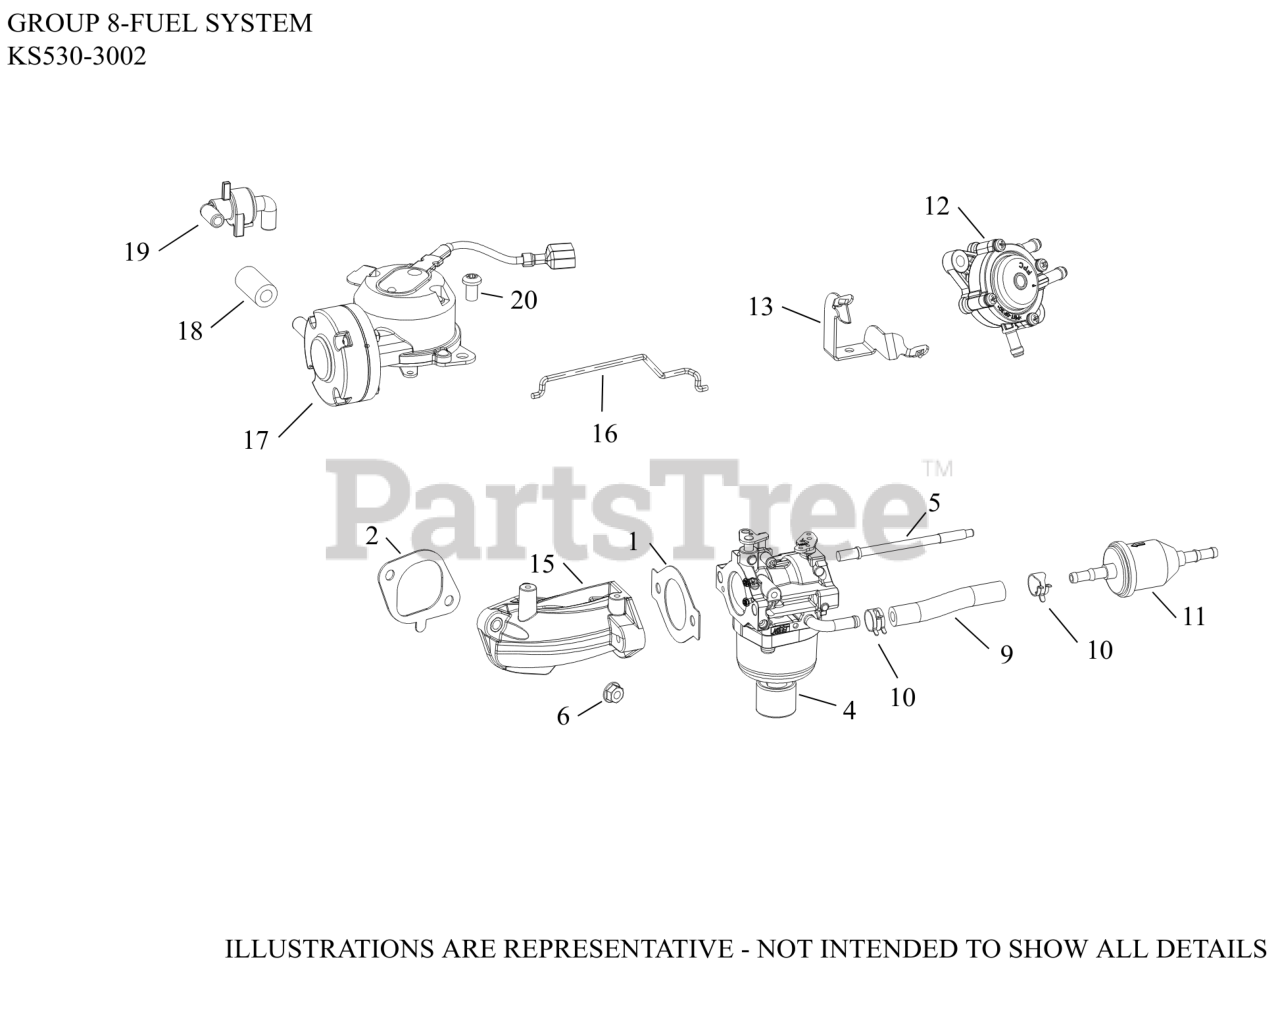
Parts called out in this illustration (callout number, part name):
1	GASKET, CARBURETOR (THROTTLE)
2	GASKET, INTAKE MANIFOLD
4	KIT,CARB(NIKKI)
5	STUD, CARBURETOR
6	NUT, FLG M6X1.0
9	HOSE,LW PERM.FUEL 24.00"-USE 25 111 81-S
10	SPRING CLAMP, HOSE
11	FILTER,FUEL 51 MICRON (FUEL PUMP)
12	PUMP, FUEL (PULSE)-(#2539326S)
13	BRACKET, FUEL PUMP
15	MANIFOLD, INTAKE ASSY
16	LINKAGE, CHOKE
17	DIAPHRAGM ASSY
18	HOSE, VACUUM
19	CHECK VALVE ASSY
20	SCREW, K40 X 1.79 TFS
NI	HIGH ALTITUDE KIT (5000 FT)
NI	KIT, OVERHAUL
NI	KIT, CHOKE SHAFT
NI	KIT, O-RING
NI	KIT, SOLENOID (NIKKI)
NI	KIT, BOWL WITH O-RINGS
NI	KIT, FLOAT & INLET NEEDLE FOR FUEL PUMP
NI	KIT, THROTTLE SHAFT
